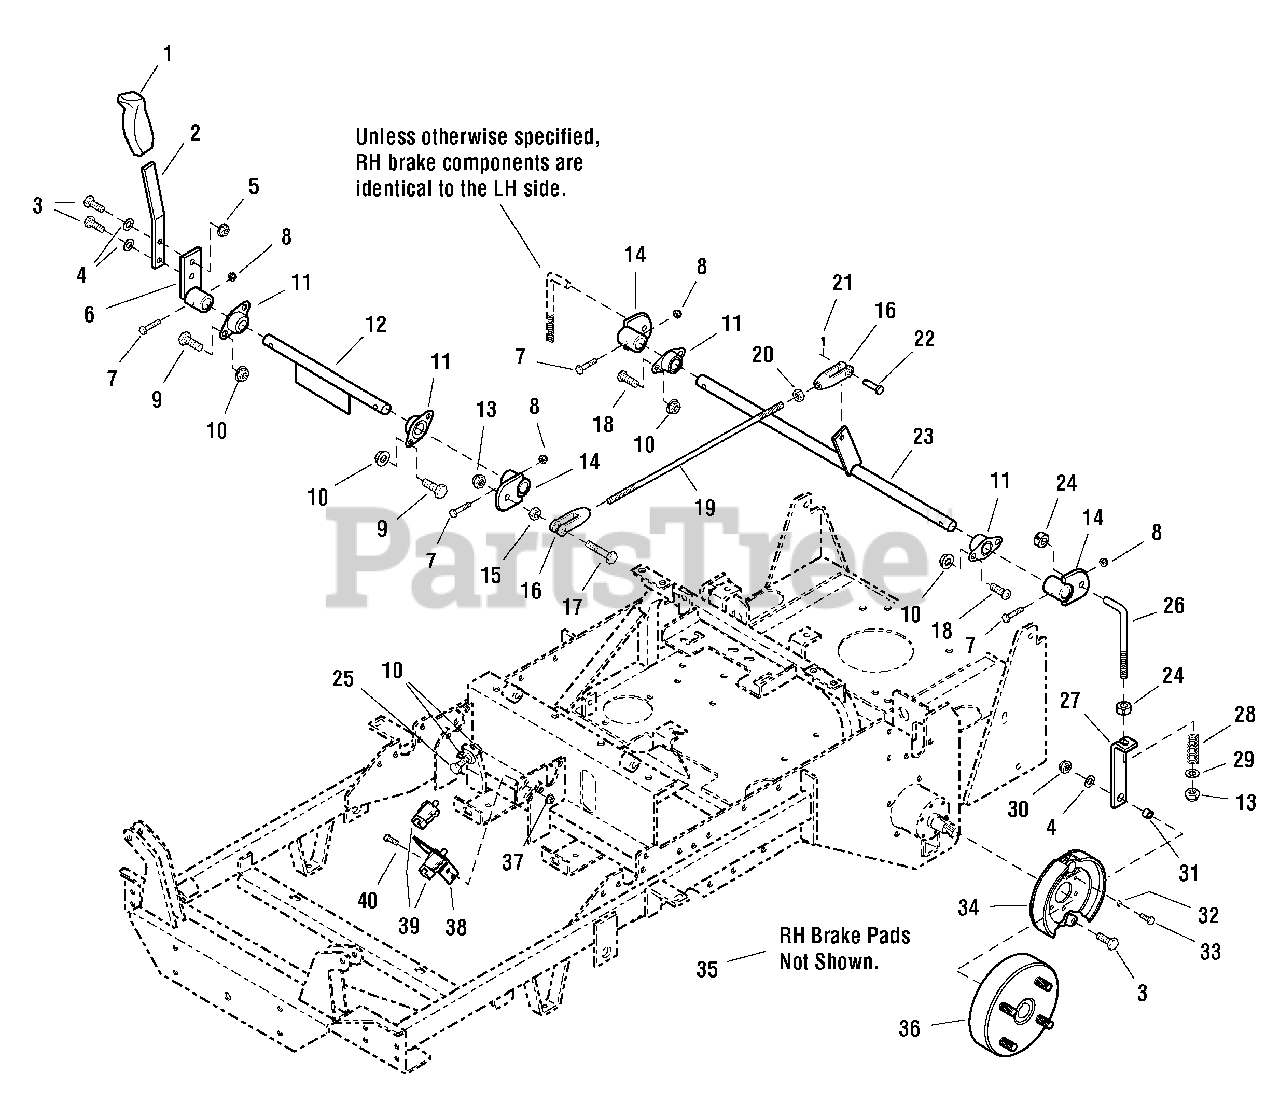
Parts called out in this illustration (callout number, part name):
2	BRAKE, Handle, Orange
2	BRAKE, Handle, Red
3	CAPSCREW, Hex Head, 5/16-18 X 1
4	WASHER, Flat, 5/16
5	NUT, Hex Serrated Flange, 5/16-18
6	MOUNT, Brake Handle, Orange
6	MOUNT, Brake Handle, Red
7	CAPSCREW, Hex Head, 1/4-20 X 1-3/4
8	NUT, Hex Nylon Lock, 1/4-20
9	CAPSCREW, Hex Head, 3/8-16 X 3/4
10	NUT, Hex Serrated Flange, 3/8-16
11	BEARING, Flange
12	BRAKE SHAFT, Front, Orange
12	BRAKE SHAFT, Front, Red
13	NUT, Hex Nylon Lock, 3/8-16
14	BRAKE, Linkage Pivot, Orange
14	BRAKE, Linkage Pivot, Red
15	NUT, Hex, 3/8-16
16	CLEVIS, 3/8-24
17	CAPSCREW, Hex Head, 3/8-16 X 2
18	CAPSCREW, Button Allen Head, 3/8-16 X 3/4
20	NUT, Hex, 3/8-24
21	PIN, Cotter
22	PIN, Clevis, 3/8 X 1
23	BRAKE SHAFT, Rear, Orange
23	BRAKE SHAFT, Rear, Red
24	COLLAR, Set, 3/8
25	CAPSCREW, Hex Head, Flange Lock Taptite, 3/8-16 X 1-3/4
26	ROD, Brake Adjustment
27	LINK, BRAKE LOCK - BLK
28	SPRING, Compression
29	WASHER, Flat, 3/8
30	NUT, Hex Nylon Lock, 5/16-18
31	PIVOT, Sleeve
32	WASHER, Lock, 1/4
33	CAPSCREW, Hex Head, M6 X 14MM
34	BRAKE ASSEMBLY, LH
36	BRAKE, Drum, 4 Bolt
37	NUT, Hex Serrated Flange, 1/4-20
38	SWITCH, Mount Bracket, Orange
38	SWITCH, Mount Bracket, Red
39	SWITCH, DP NO/NC SNAP-IN
40	BOLT,1/4-20X5/8
